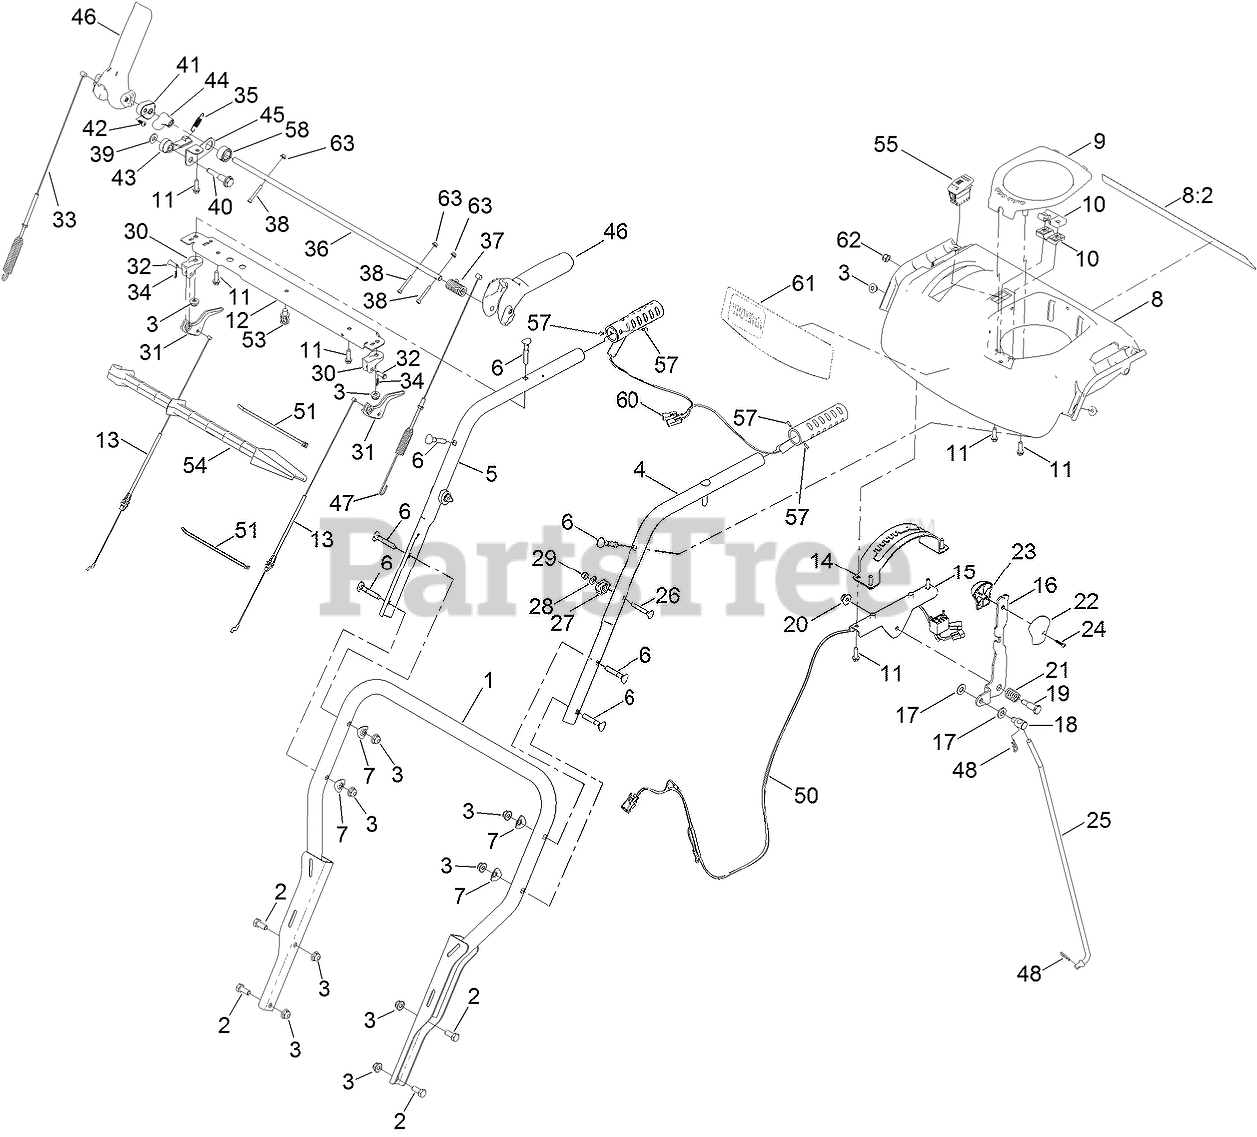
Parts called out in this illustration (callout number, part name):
1	LOWER HANDLE ASM
2	SCREW-HH
3	NUT-HF
4	HANDLE-UPPER, LH
5	HANDLE-UPPER, RH
6	SCREW-HANDLE
7	WASHER-CUP
8	PANEL-CONTROL
8:2	DECAL-SAFETY
9	COVER-QUICKSTICK
10	SUPPORT-ROD
11	SCREW-PLASTITE, HWH
12	BRACE-CONSOLE
13	CABLE-CLUTCH
14	GATE-SHIFT
15	BRACKET-SHIFT
16	SELECTOR-SPEED
17	WASHER-FLAT
18	TRUNNION-ROD
19	SCREW-SHOULDER, HH
20	NUT-HF
21	SPRING-COMPRESSION
22	KNOB-SHIFT, LH
23	KNOB-SHIFT, RH
24	SCREW-PPH
25	ROD-SHIFT
26	BOLT-CARR
27	CLAMP-CABLE
28	WASHER-PLAIN
29	NUT-HEX
30	MOUNT-LEVER, CLUTCH
31	LEVER-CLUTCH
32	PIN-CLEVIS
33	CABLE-AUGER
34	PIN-HAIR
35	SPRING-LOCKOUT, HANDLE
36	ROD-LOCKOUT
37	SPRING-TORSION, HANDLE RETURN
38	SCREW-HSH
39	WASHER-FLAT
40	SCREW-SHOULDER
41	LOCK-HANDLE
42	SCREW-PPH
43	LATCH-LOCKOUT
44	CAM-LOCKOUT
45	LINK-LOCKOUT
46	LEVER-CONTROL
47	CABLE-TRACTION
48	PIN-HAIR
50	HARNESS-WIRE, LED AND HAND WARMERS
51	TIE-CABLE
53	CLIP-TIE
54	STICK-CLEANOUT
55	SWITCH-ROCKER, ON-NONE-OFF (HEATER)
57	RIVET-POP
58	COLLAR-CAM
60	GRIP-HEATED
61	DECAL-CONSOLE
62	NUT-HEX
63	NUT-LOCK ROHS
